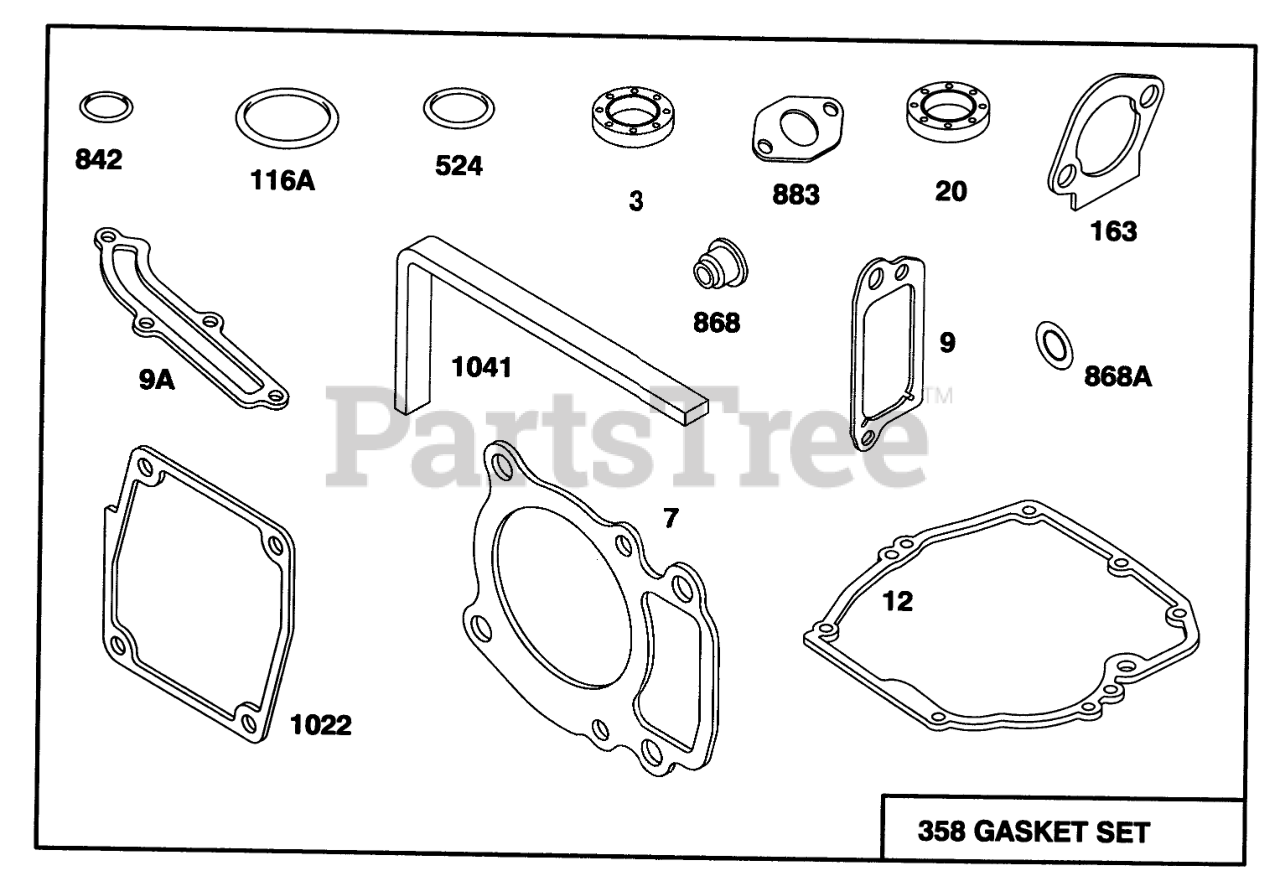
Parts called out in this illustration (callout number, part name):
3	SEAL - OIL
7	CYLINDER HEAD GASKET
9	BREATHER GASKET
9A	GASKET-BREATHER
12	ENGINE BASE GASKET
20	SEAL-OIL
116A	O RING SEAL
163	AIR CLEANER GASKET
358	GASKET SET
524	O-RING
842	O-RING
868	SealAssy-Valve
868A	Seal-Valve
883	EXHAUST GASKET
1022	ROCKER COVER GASKET
1041	SEAL - FOAM
